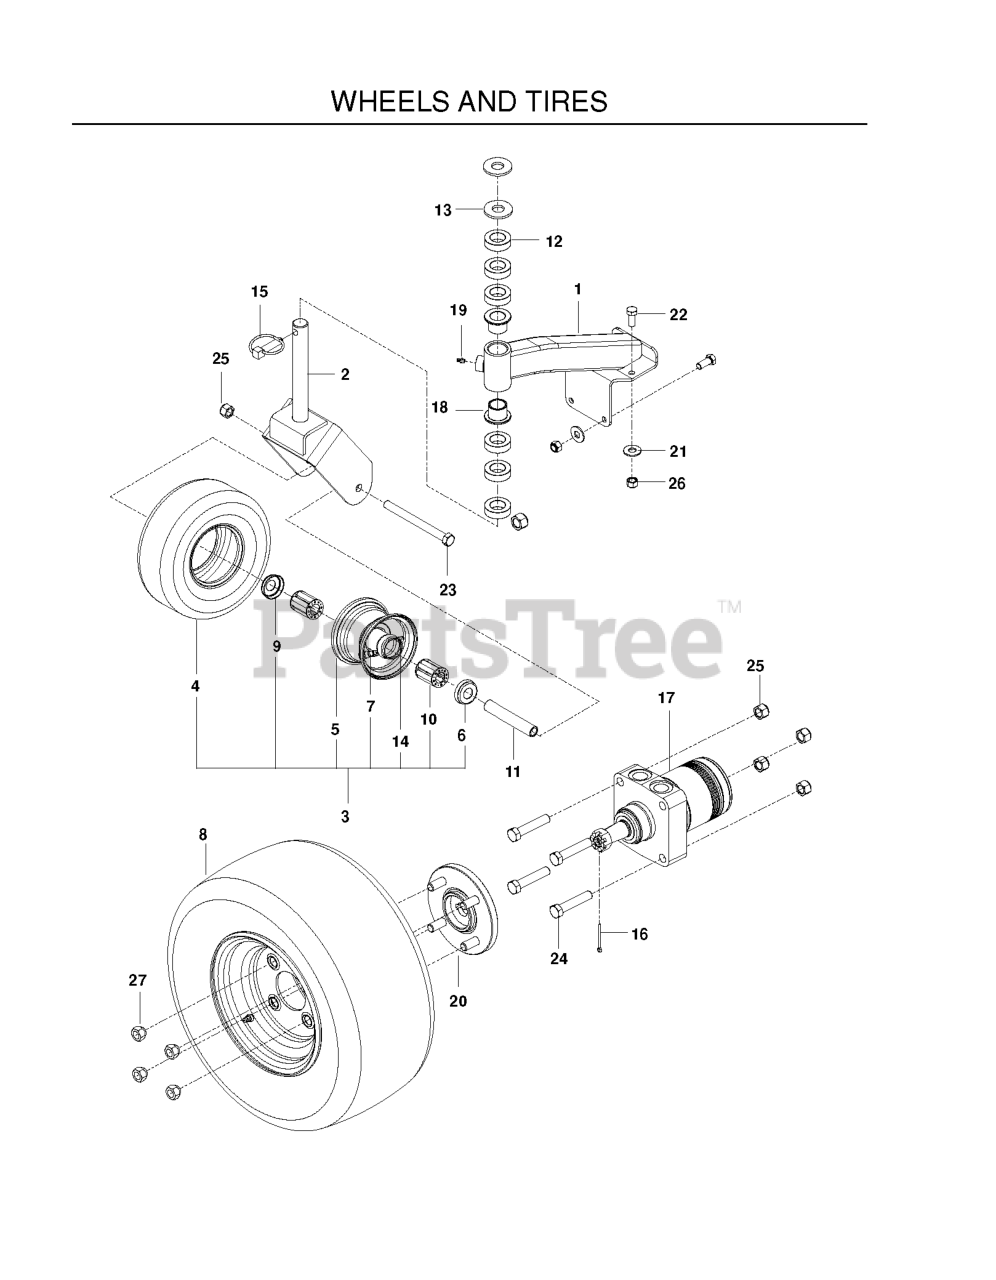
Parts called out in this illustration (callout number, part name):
1	CASTER SUPPORT ORANGE
2	CASTER WELDMENT PAINTED
3	TIRE/WHEEL.CASTER.9X3.5-4.SMOO
4	TIRE 9 X 3.5 - 4
6	ENDCAP
7	VALVE STEM TR-412
8	WHEEL ASSY, 16 X 7.5-8 OFFSET
9	ENDCAP, NOTCHED
10	ROLLER BEARING
13	SPACER, .25 HEIGHT ADJ
14	GREASE ZERK
15	LYNCH PIN 7/16
16	COTTER PIN
17	WHEEL MOTOR
18	BSHG 1.003X1.252X1.75 LG OIL
19	ZERK
20	HUB, WHEEL
21	WASHER 3/8 FLAT
22	HCS 3/8-16 X 7/8 GR 5 ZD
23	HCS 1/2C X 5 1/2
24	HEX SCREW 1/2-13 X 2.5" GR 5
25	NUT 1/2-13 HEX NYLOC ZD
26	NUT 3/8-16 NYLOC
27	LUG NUT 1/2F
